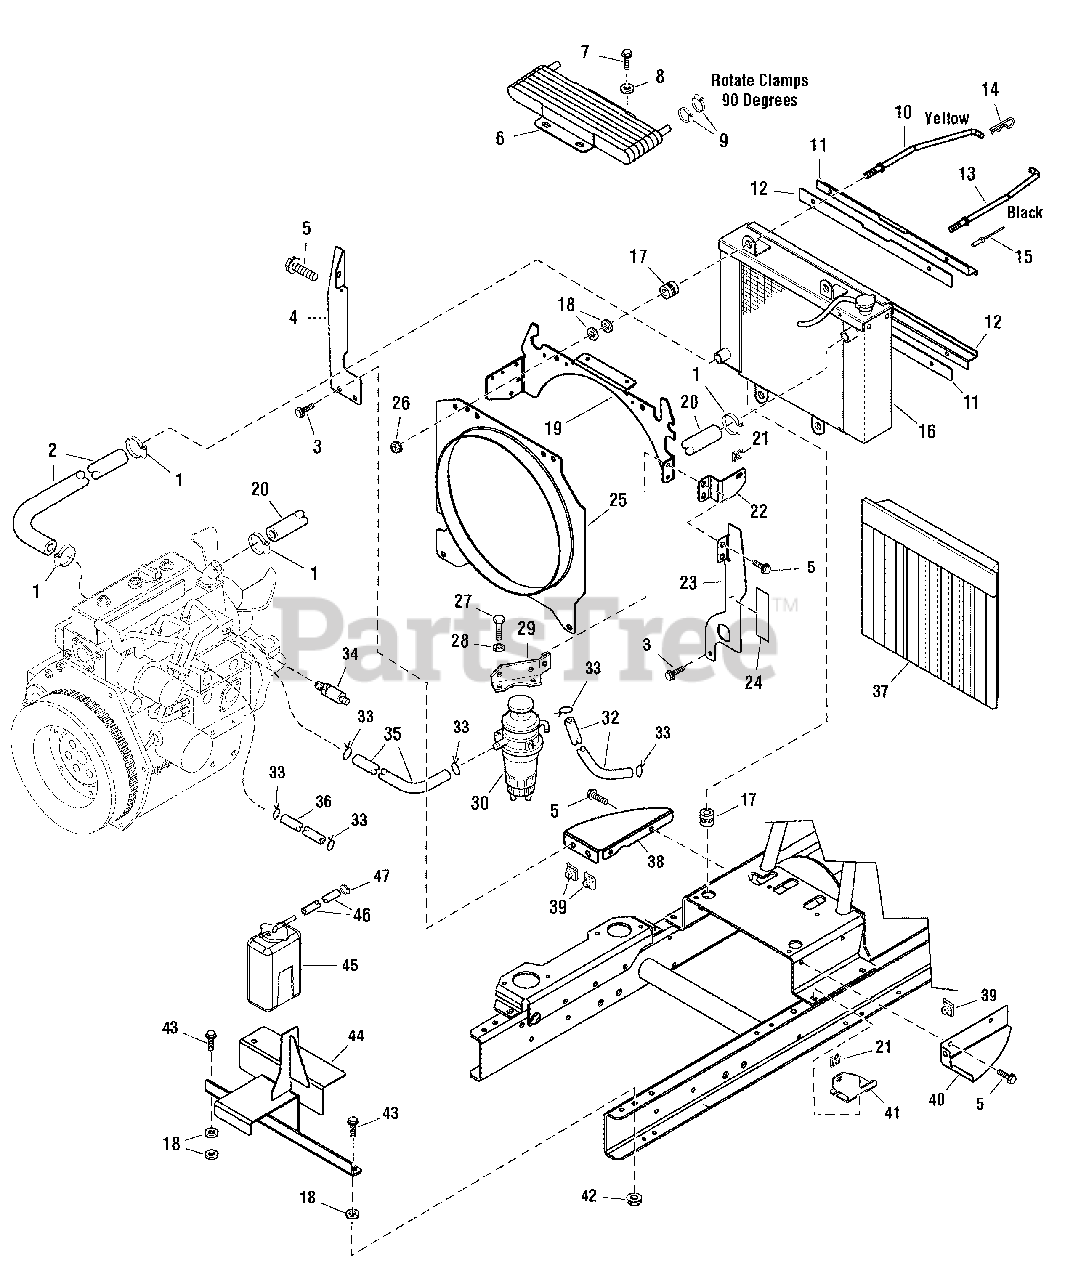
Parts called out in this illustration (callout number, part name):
1	CLAMP, Hose, Worm
2	HOSE, Radiator
3	SCREW, Hex, Whiz Lock, Flange, 5/16-16 x 1-1/4
4	SHIELD, R.H., 16GA
5	SCREW, Hex, Washer Head, Taptite, 5/16-18 x 3/4
6	COOLER ASSEMBLY, Oil
7	SCREW, Hex, Washer Head, Taptite, 1/4-20 x 1/2
8	WASHER, 1/4
9	CLAMP, Hose
10	ROD, Radiator, R.H.
11	SLIDE, Offset, 14GA
12	SLIDE, Screen Flat, 14GA
13	ROD, Radiator, L.H.
14	PIN, Quick
17	SPACER
18	WASHER, 3/4
19	SUPPORT, Radiator Shroud, 10GA
20	HOSE, Radiator
21	CLIP, 1/4 Turn Push
22	COVER, Bracket, Top, 12GA
23	SHIELD, L.H., 16GA
24	DECAL, Clean Radiator
25	SHROUD, Radiator
26	NUT, Hex, Flange, 3/8-16 ESNA
27	CAPSCREW, Hex Head
28	LOCKWASHER, Spring, 5/16
29	BRACKET, Fuel Filter
30	FUEL FILTER ASSEMBLY
31	FILTER, Fuel
33	CLAMP, Hose, Type E
34	SENDER, Temperature
36	HOSE, Fuel (Cut to 71.5)
37	SCREEN, Corrugated, 20GA
38	BAFFLE, R.H., 16GA
39	NUT, Speed, 5/16-18, Lug Type
40	BAFFLE, L.H., 16GA
41	COVER, Bracket, Bottom
42	NUT, Hex, KEPS, 3/8-16 Conical Washer
43	SCREW, Hex, Whiz Lock, Flange, 3/8-16 x 1-1/4
44	HOLD DOWN ASSEMBLY, Battery
45	RADIATOR, Overflow
46	HOSE, Radiator Overflow
47	CLAMP, Hose OETIKER 15/32
